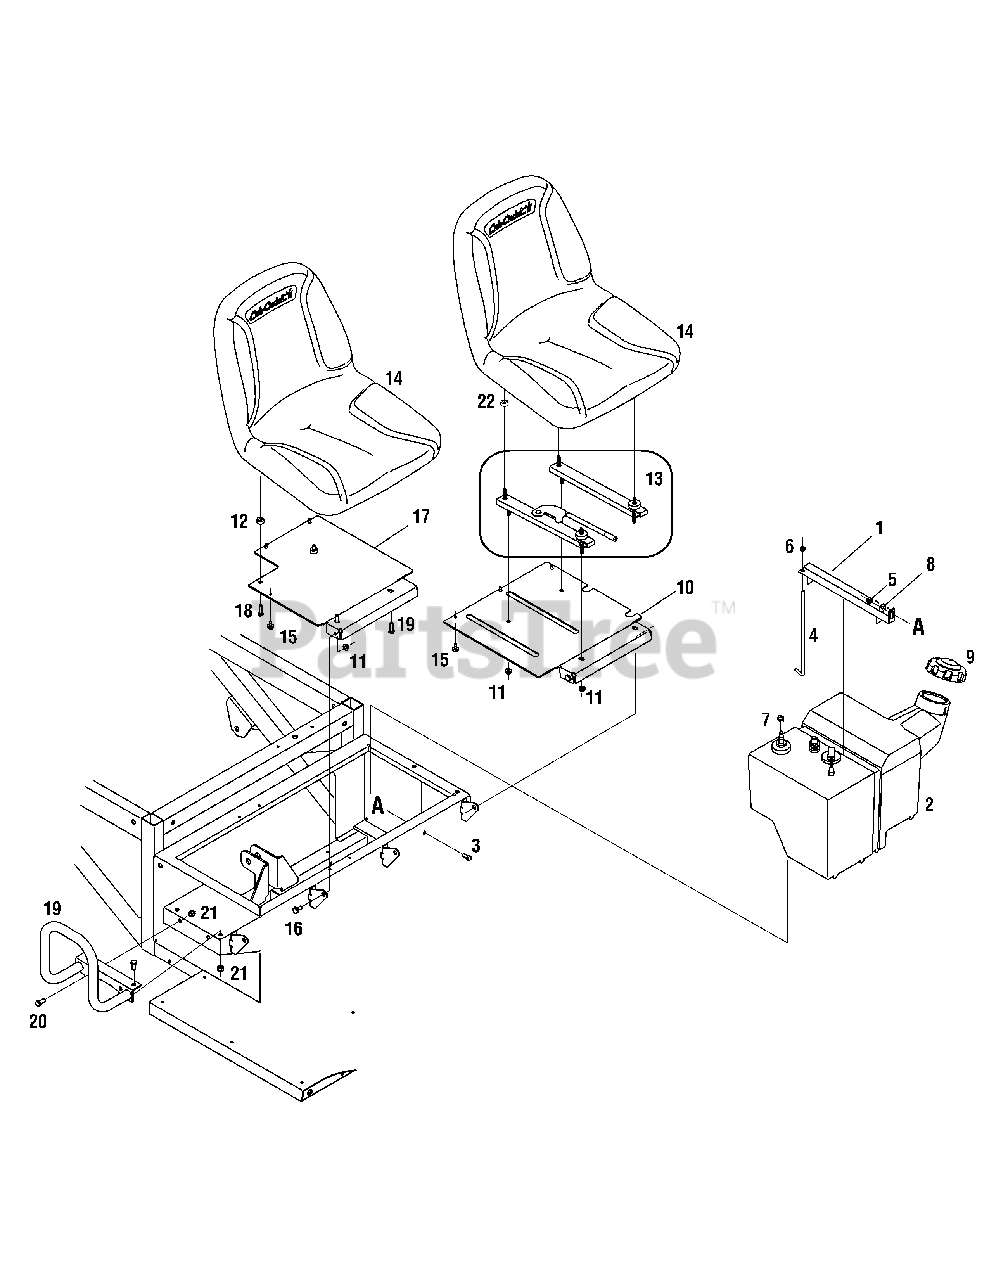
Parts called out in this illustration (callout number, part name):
1	Bracket Assembly, Fuel Tank
2	Tank Assembly, Fuel (Incl. valve, grommets, cap. switch & fitting)
3	Hex Screw, 5/16-18 x .75
4	Hold-down Rod, Fuel Tank
5	Sems Nut, 5/16-18
6	Nut, Flange Lock, 1/4-20
7	Clamp, Hose
8	Washer, .349 x .879 x .063
9	Cap, Fuel
10	Plate, Seat, LH
11	Nut, Flange Lock, 5/16-18, Gr5
12	Spacer, Seat
13	Track Assembly, Seat
14	Seat
15	Bumper
16	Shoulder Screw, .435 x .178-5/16 x .56
17	Plate, Seat, RH
18	Hex Screw, 5/16-18 x 1.0
21	Nut, Hex Lock Nylon, 3/8-16
22	Spacer, Seat
23	Fuel Tank Gasket
